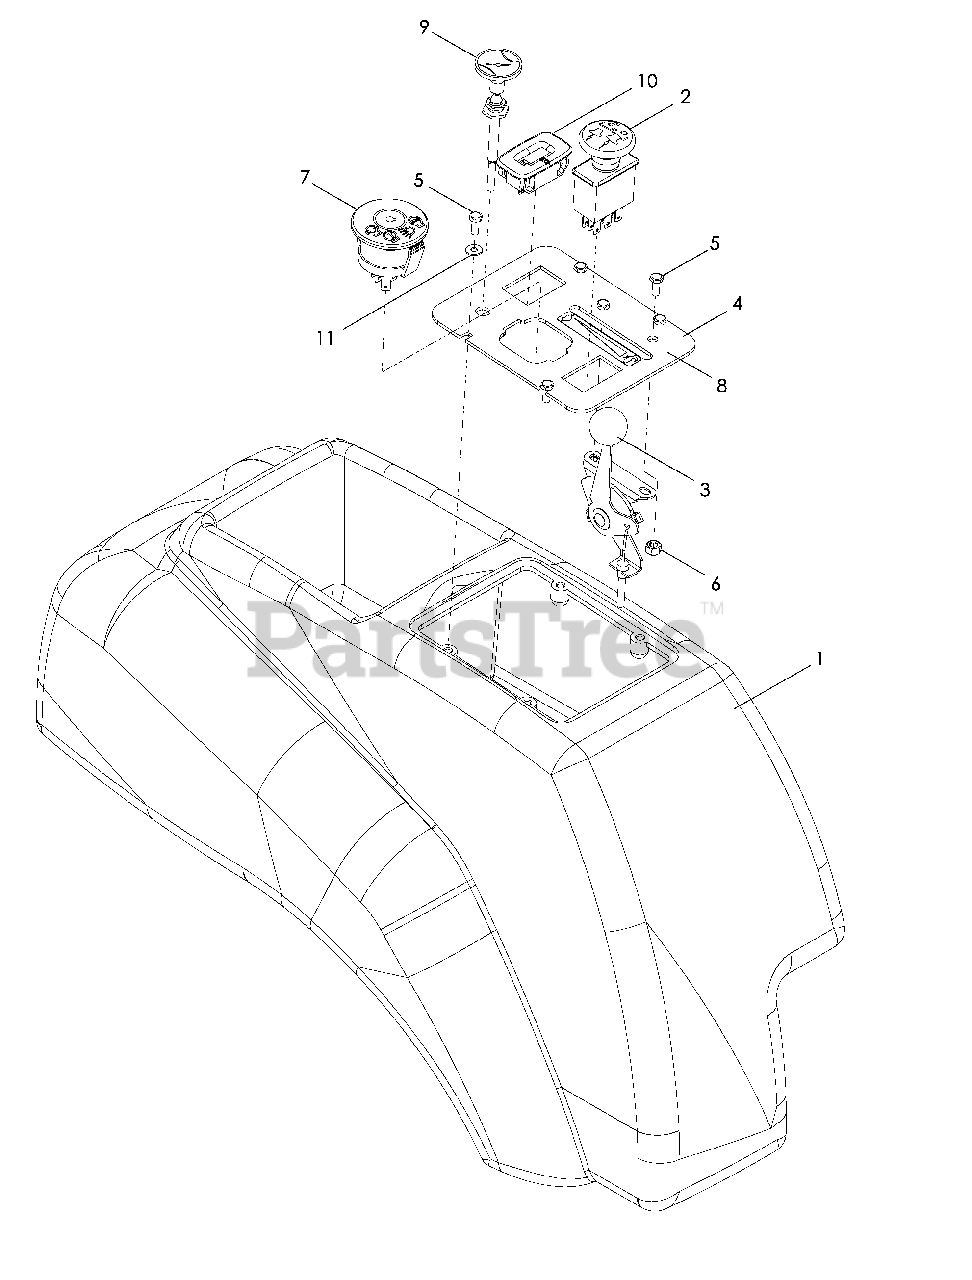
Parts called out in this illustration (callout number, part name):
2	SWITCH, CLUTCH
3	CABLE, THROTTLE
4	PLATE, CONSOLE
5	HCS #10-24 x ½
6	NUT #10-24 NYLOC
7	SWITCH, IGNITION
8	DECAL, THROTTLE
9	CONTROL, CHOKE
10	METER, HOUR
11	WASHER #10
